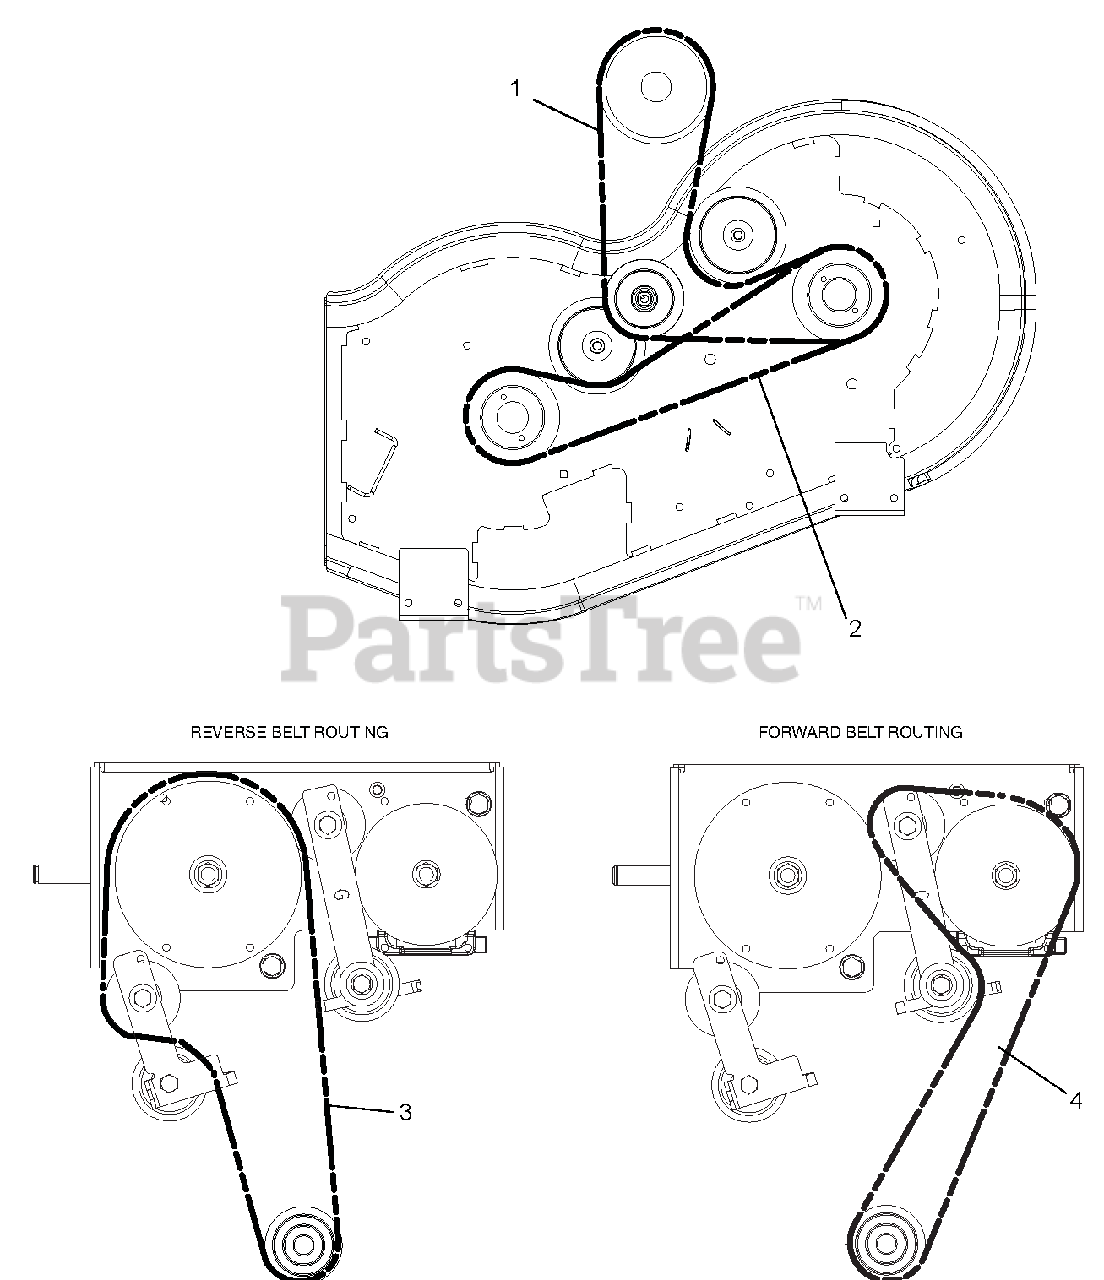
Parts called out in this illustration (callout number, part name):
1	V-BELT, HA WRAPPED
2	V-BELT, HA-WRAPPED
3	V-BELT, 3L-WRAPPED
4	V-BELT, 3L-WRAPPED
